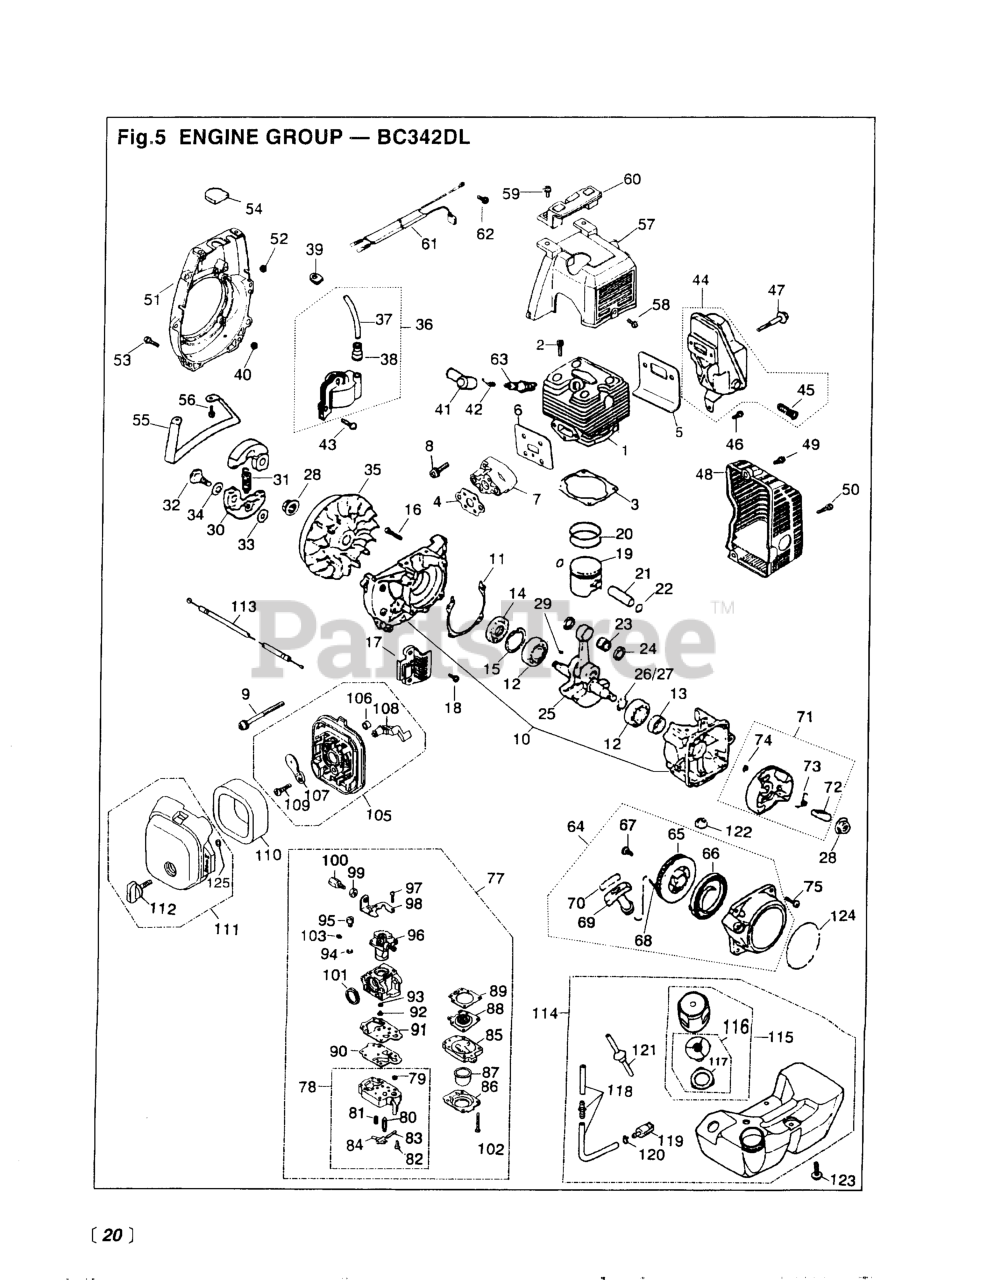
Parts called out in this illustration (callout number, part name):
1	CYLINDER (RPLS -12111)
2	BOLT M5 x 20 (RPLS -12280)
3	GASKET
8	SCREW, M5 x 25
9	SCREW, M5 X 55
10	CRANKCASE (RPLS -21101)
13	SEAL, OIL (RPLS 1100-21210)
14	SEAL, OIL (RPLS 1200-21220)
15	RING, SNAP, M32 x 1.2
16	BOLT, M5 X 30
17	GUARD (RPLS-21310)
18	SCREW,M5 X 14 (RPLS 1400-15510
19	PISTON (RPLS 1650-41111)
20	RING, PISTON
21	PIN
22	RING, SNAP
23	BEARING
24	WASHER (RPLS 3310-41341)
25	CRANKSHAFT CO
26	SHIM (NO LONGER AVAILABLE)
29	KEY
30	SHOE, CLUTCH (RPLS -51110)
31	SPRING, CLUTCH
32	SCREW
33	WASHER
34	WASHER (USE -51241)
36	COIL ASSEMBLY
39	GROMMET
42	SPRING
43	SCREW, M5X20 (RPLS.1400-75510)
44	MUFFLER ASSEMBLY
45	ARRESTER
46	SCREW, M5 X 12
48	COVER, MUFFLER
49	BOLT M5 x 20 (RPLS -12280)
50	BOLT
51	COVER, FAN
53	BOLT M5 x 20 (RPLS -12280)
56	BOLT (REPLACES 01252-30514)
57	COVER, CYLINDER (RPLS-32112)
58	SCREW, M5 X 12
59	SCREW, M5X20 (RPLS.1400-75510)
60	HEAD GUARD
61	CORD COMP
62	SCREW, M5 X 12
64	RECOIL ASSEMBLY
65	REEL
66	SPRING, SPIRAL
67	SCREW (RPLS -75150)
69	KNOB
71	PULLEY ASSEMBLY
72	RATCHET
73	SPRING, RETURN
74	E-RING
75	SCREW, M5X20 (RPLS.1400-75510)
77	CARBURETOR ASSEMBLY (WYJ-118)
78	BODY, PUMP
80	VALVE, INLET
81	SPRING, METERING LEVER
82	SCREW, METERING LEVER PIN
83	PIN, METERING LEVER
84	LEVER
85	BODY, PURGE
86	COVER, PUMP
87	PUMP, PRIMING
88	DIAPHRAGM (USE 4810-81260)
89	GASKET, DIAPHRAGM
90	DIAPHRAGM
91	GASKET, PUMP
92	JET
93	RING, O
94	RING
95	SWIVEL
96	VALVE ASSY
97	SCREW
99	NUT, CABLE ADJUSTER
101	RING, PACKING
102	SCREW
103	WASHER
106	SLEEVE
107	PLATE, CHOKE (RPLS-82130)
108	LEVER, CHOKE
109	SCREW (REPLACES 50030272)
110	ELEMENT
112	KNOB (RPLS -82220)
113	CABLE COMP (RPLS 1633-83100)
116	VALVE COMPLETE
117	PACKING (RPLS -85321)
118	PIPE (RPLS 1601-85403)
119	FILTER ASSY
120	CLIP (REPLACES 2841-31280)
121	PIPE (RPLS 1601-85701)
122	WASHER
123	SCREW, M5 X 22
124	LABEL BC342DL (RPLCS. -75411)
125	RING
